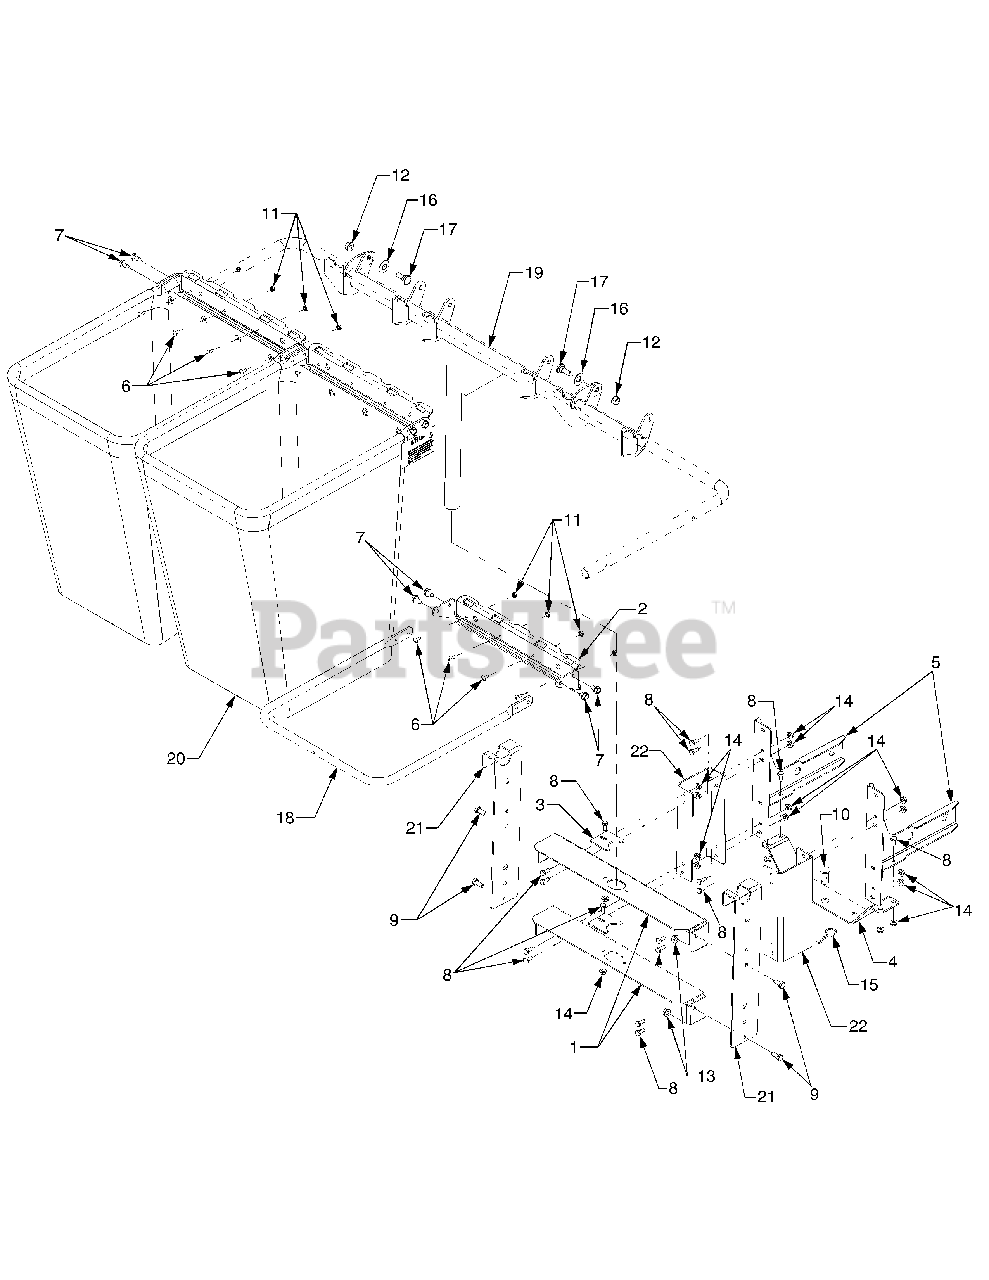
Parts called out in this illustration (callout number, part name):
1	Bracket, Catcher Support
2	Bracket, Bag Frame Hanger
3	Bracket, Support Tube Adapter ..
5	Bracket, Frame Support
6	Screw, Truss Hd. Mach. 10-24 x .5
7	Screw, Hex Wash. Hd. Tapp 5/16-18 x .625
8	Screw, Hex Cap 1/4-20 x .62 GR5
9	Screw, Hex Cap 5/16-18 x .75 GR5
10	Pin, Clevis, .62 Diam.
11	Nut, Hex Sems, 10-24
12	Nut, Hex Flange Lock, 3/8-16
13	Nut, Hex Flange Lock, 5/16-18 ...
14	Nut, Hex Flange Lock, 1/4-20
15	Pin, Internal Cotter
16	Washer, Belleville, .51 x 1.14 x .04
17	Screw, Shoulder .50 x .27: 3/8-16
18	Tube, Grass Bag Frame
19	Support Tube Assembly
20	Bag, Grass Catcher
21	Bracket, Tube Assembly Support
22	Bracket, Spacer
